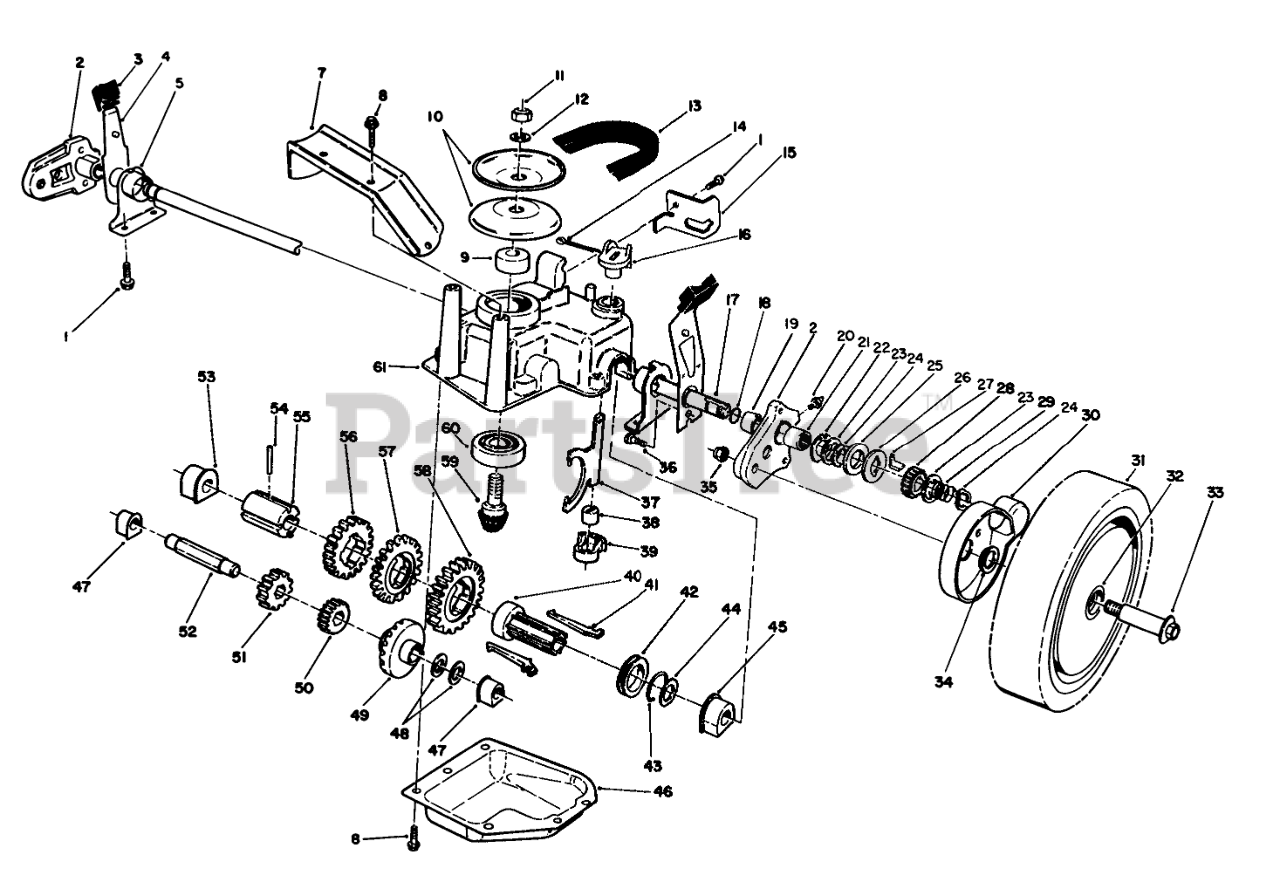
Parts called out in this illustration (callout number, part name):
1	SCREW-HWHTF
2	Pivot Arm Assembly (Incl. Ref. #19-21)
3	KNOB-ARM
4	SPRING ARM ASM
5	CAP-END
7	Bracket-BeltGuide
8	SCREW-HWHTF
9	SPACER
10	Pulley Half
11	NUT-HEX
12	WASHER-FLAT
13	V-BELT
14	PIN-COTTER
15	RETAINER-CABLE
16	LEVER-SHIFT
17	SHAFT-OUTPUT
18	O-RING
19	BUSHING
20	FITTING-GREASE
21	BEARING-ROLLER
22	WASHER-ARM, PIVOT
23	WASHER-THRUST, KEYED
24	RING-CLIP, LOCKING
25	RING-FRICTION
26	WASHER-CLUTCH
27	KEY-ROCKING, LH
28	GEAR-PINION
29	SPRING-COMPRESSION
30	COVER-WHEEL
31	Wheel Tire & Gear Assy. (Incl. Ref. #32)
32	BUSHING
33	WHEEL BOLT
34	SPACER-COVER, WHEEL
35	NUT-LOCK
36	SCREW-HSH, THREAD FORMING
37	YOKE-SHIFT
38	BUSHING-YOKE
39	RETAINER-FORK, SHIFT
40	SLEEVE-KEY, SHIFT
41	KEY-SHIFT
42	COLLAR-SHIFT
43	CLIP-SPRING
44	WASHER-PLAIN
45	BUSHING-OUTPUT
46	Cover-Gearcase
47	BUSHING
48	WASHER-THRUST
49	Gear-Bevel
50	PINION-20T
51	PINION-25T
52	SHAFT-INTERMEDIATE
53	BUSHING
54	PIN-SPRING
55	SLEEVE-GEAR
56	GEAR-39T
57	GEAR-44T
58	GEAR-49T
59	Gear-Pinion
60	BEARING-BALL
61	CASE-GEAR, UPPER
